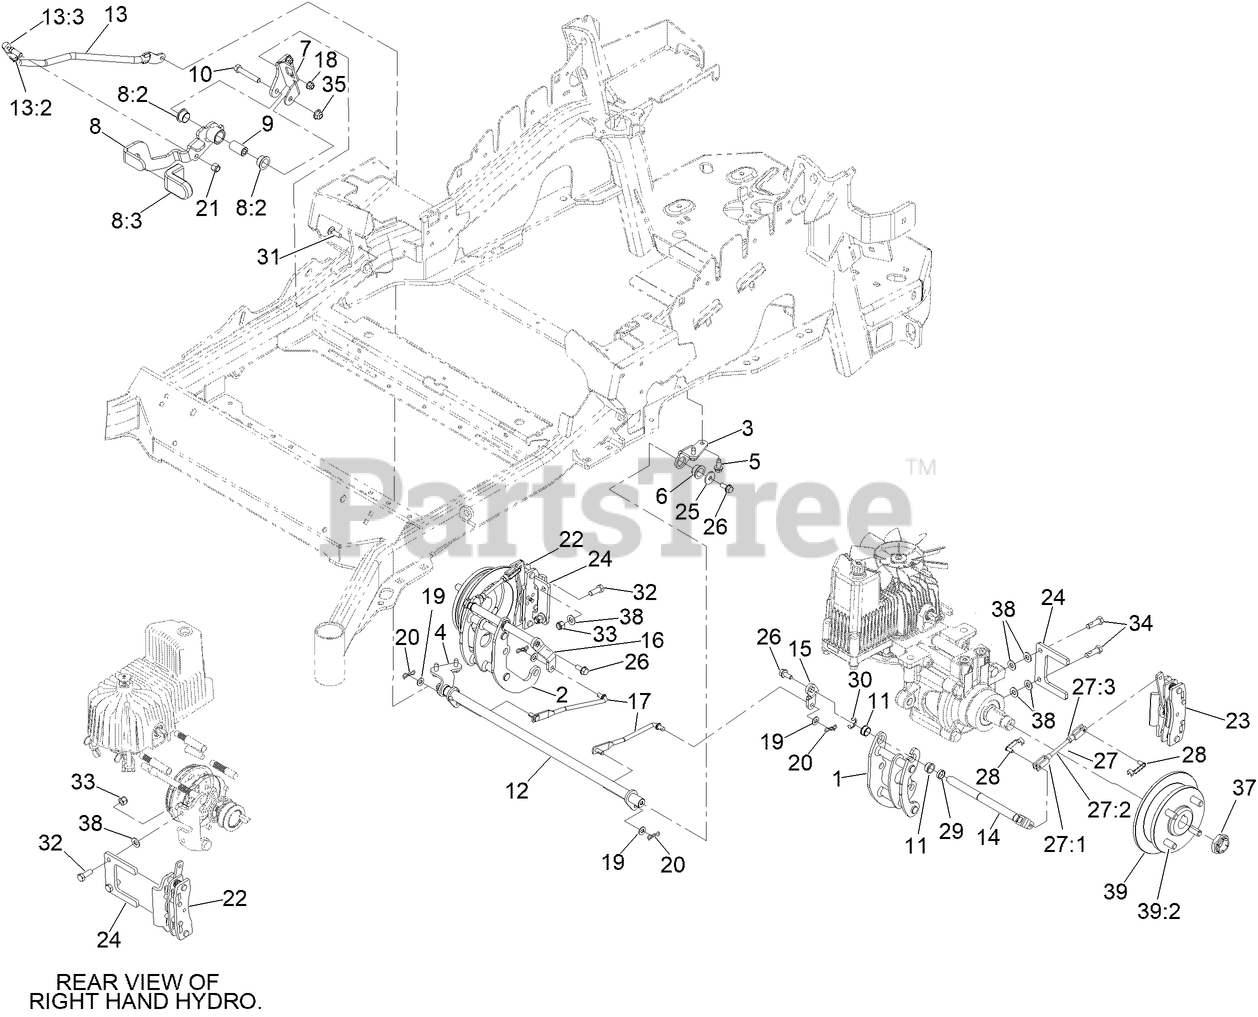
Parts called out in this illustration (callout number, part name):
1	MOUNT-BELLCRANK, LH
2	MOUNT-BELLCRANK, RH
3	MOUNT-PIVOT, LH
4	MOUNT-PIVOT, RH
5	SCREW-HWHTF
6	BUSHING-FLANGE
7	BRACKET-MOUNT
8	BRAKE LEVER ASM W/GRIP M-R
8:2	BUSHING-FLANGE
8:3	GRIP-LEVER
9	HANDLE-PIVOT, BRAKE
10	SCREW-HH
11	BUSHING
12	SHAFT-CROSS
13	ASM, FRONT LINKAGE
13:2	END-TIE ROD, RH
13:3	NUT-HJ
14	BELLCRANK
15	ARM-INNER, RH
16	ARM-INNER, LH
17	MID-LINK, LONG
18	NUT-HF, NI
19	WASHER-PLAIN
20	PIN-COTTER, LOCKING
21	NUT-LOCK
22	CALIPER-BRAKE, RH
23	CALIPER-BRAKE, LH
24	PLATE-MOUNT, BRAKE
25	WASHER-FLAT
26	SCREW-HHF
27	REAR LINKAGE ASM
27:2	LINKAGE, REAR
27:3	NUT-JAM
28	PIN-CLEVIS, SPRING
29	SPACER
30	E-RING
31	BOLT-CARR
32	SCREW-HH,
33	NUT-LOCK
34	SCREW-HH, PATCH,
35	NUT-HF, NI
37	LOCKNUT
38	WASHER-FLAT
39	WHEEL HUB ASM
39:2	STUD-WHEEL
